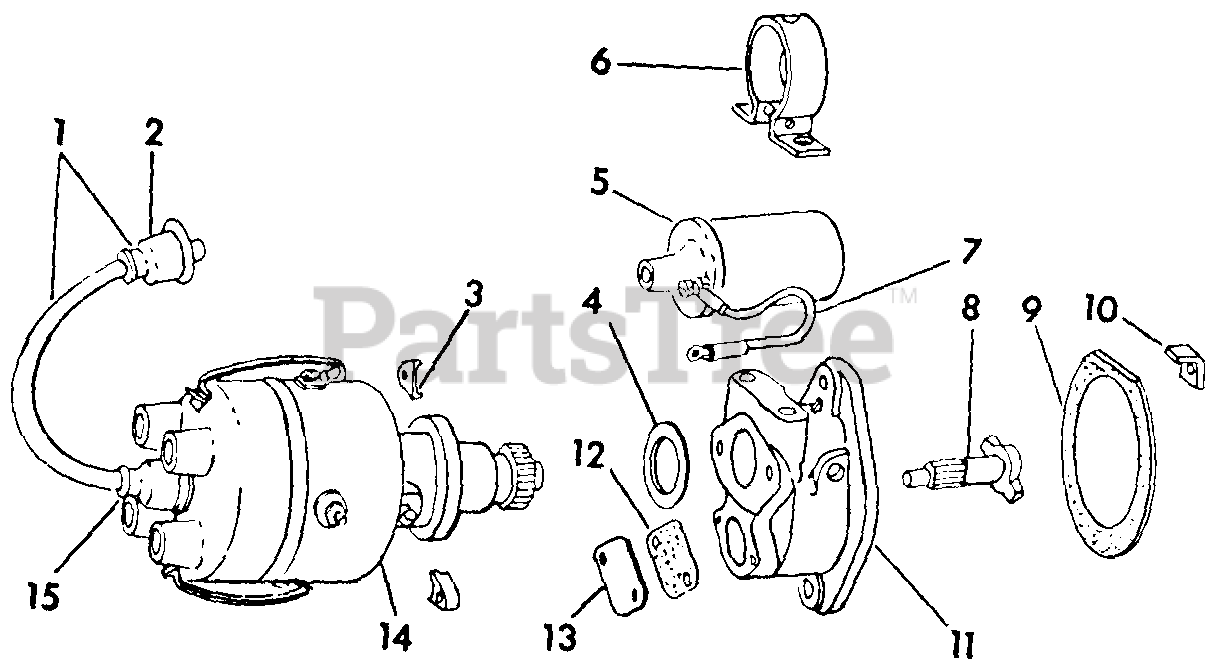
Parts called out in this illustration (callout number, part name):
1	CABLE ASSY, COIL TO DISTRIBUTOR
1	CABLE, COIL TO DISTRIBUTOR W/NIPPLES
2	NIPPLE, IGNITION COIL
3	CLAMP, DISTRIBUTOR
4	GASKET, DISTRIBUTOR
5	PACKAGE, IGNITION COIL SERVICE
6	CLAMP, IGNITION COIL
7	CABLE ASSY, COIL TO DISTRIBUTOR PRIMARY
8	SHAFT ASSY, DISTRIBUTOR DRIVE
9	GASKET, DISTRIBUTOR DRIVE HOUSING
10	NOT USED IN THIS APPLICATION
11	HOUSING ASSY, DISTRIBUTOR DRIVE
11	PACKAGE, DISTRIBUTOR DRIVE HOUSING AND COVER SERVICE
12	GASKET, DISTRIBUTOR DRIVE HOUSING HOLE COVER
13	COVER, DISTRIBUTOR DRIVE HOUSING HOLE
14	DISTRIBUTOR ASSEMBLY
15	NIPPLE, DISTRIBUTOR CAP TERMINAL
